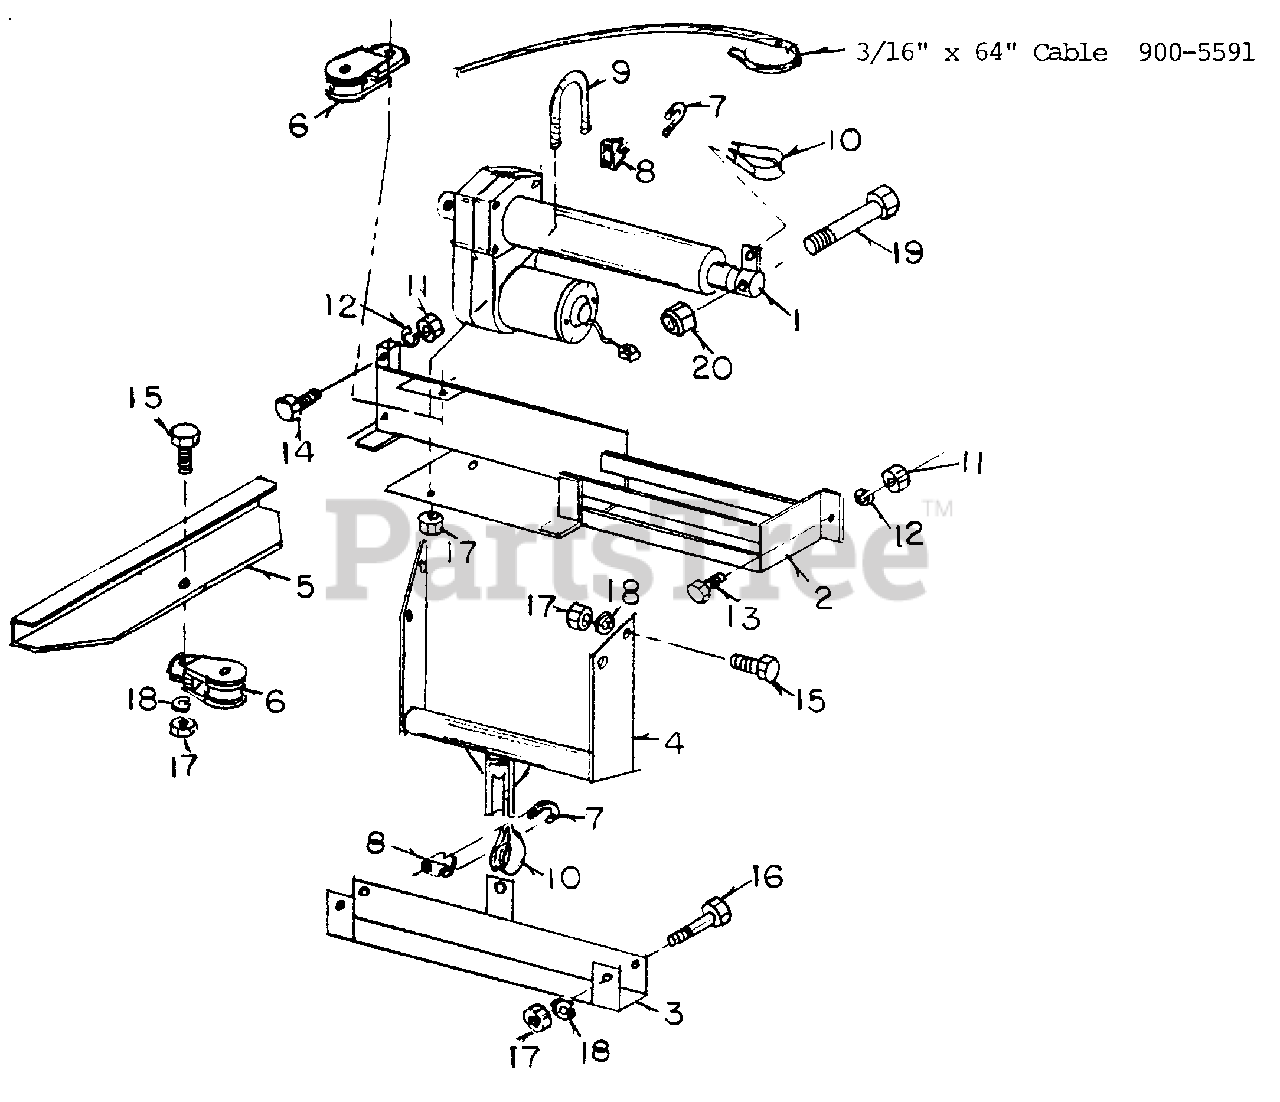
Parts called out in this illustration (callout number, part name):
1	Actuator
2	Actuator Mount
3	Deck Lift Adapter
4	Cable Mount
5	Cable Mount
7	U-Bolt
9	U-Bolt
11	3/4-20 Nuts
12	3/4 Lock Washers
13	1/4-20 x 3/4
14	1/4-20 x 1
15	5/16-18 x 1
16	5/16-18 x 2
17	5/16-18 Nut
18	5/16 Lock Washers
19	1/2-13 x 4
20	1/2-13 Lock Nut
